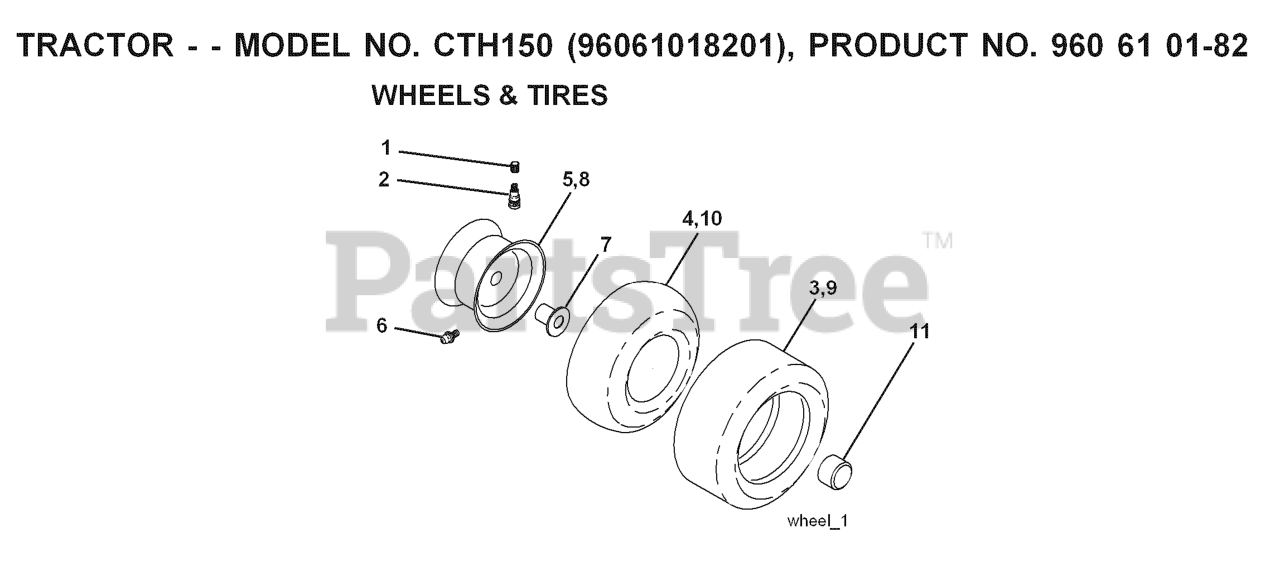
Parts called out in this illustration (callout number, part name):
2	VALVE STEM LT
3	TIRE HEAVY DUTY
4	TUBE.5.3/4.5/6
5	RIM ASM 6" FRONT SILVER
6	FITTING LT
7	BEARING T
8	RIM ASM 8" REAR SILVER
9	TIRE.TS.20X10-8
10	TUBE
11	CAP, AXLE BLK
